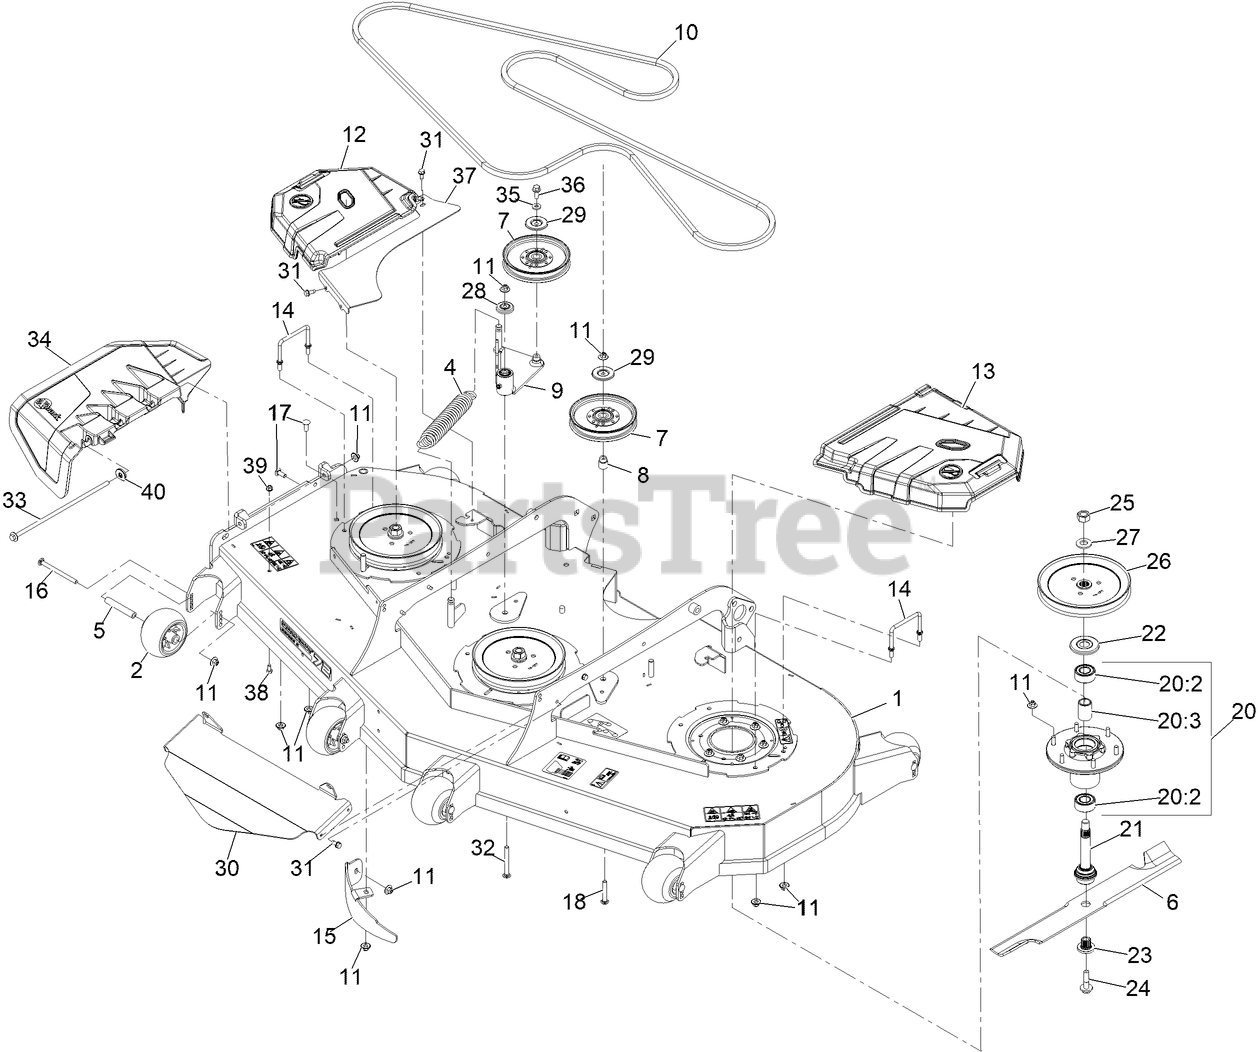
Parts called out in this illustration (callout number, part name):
1	ASM-DECK W/DECALS 726
2	ROLLER-SCALP, ANTI
4	SPRING-EXTENSION
5	SPACER-AXLE
7	IDLER-PULLEY
8	BUSHING-IDLER
9	IDLER ARM ASM
10	BELT - 5V 171.5
11	Nut-Nyloc 3/8-16 Flg
12	SHIELD, RT
13	SHIELD, LT
14	WIREFORM-COVER
15	BAFFLE-DOGLEG, LZ72
16	BOLT-CARR
17	SCREW-CARR
18	SCREW-CARR
20	ASM-CUTTER HSG
20:2	BEARING-3205 TRASHGUARD
20:3	SPACER-BEARING
21	ASM-SPINDLE AND SEAL
22	GUARD-BEARING, TOP
23	BUSHING,SPLINED
24	SCREW,SEMS 1/2-20 X 2.19
25	NUT-HEX
26	SHEAVE,BLADE DRIVE 8.74
28	GUARD-TOP
29	SHIELD-DUST
30	GUARD-FRONT DECK 72
31	SCREW-THD ROLL, HWH
32	SCREW-CARR
33	Pin, Chute
34	Chute-Deck Discharge
36	SCREW-HHF
37	COVER-RH BELT 72
38	SCREW-HH
39	NUT-HF, NI
40	Retainer, Chute
